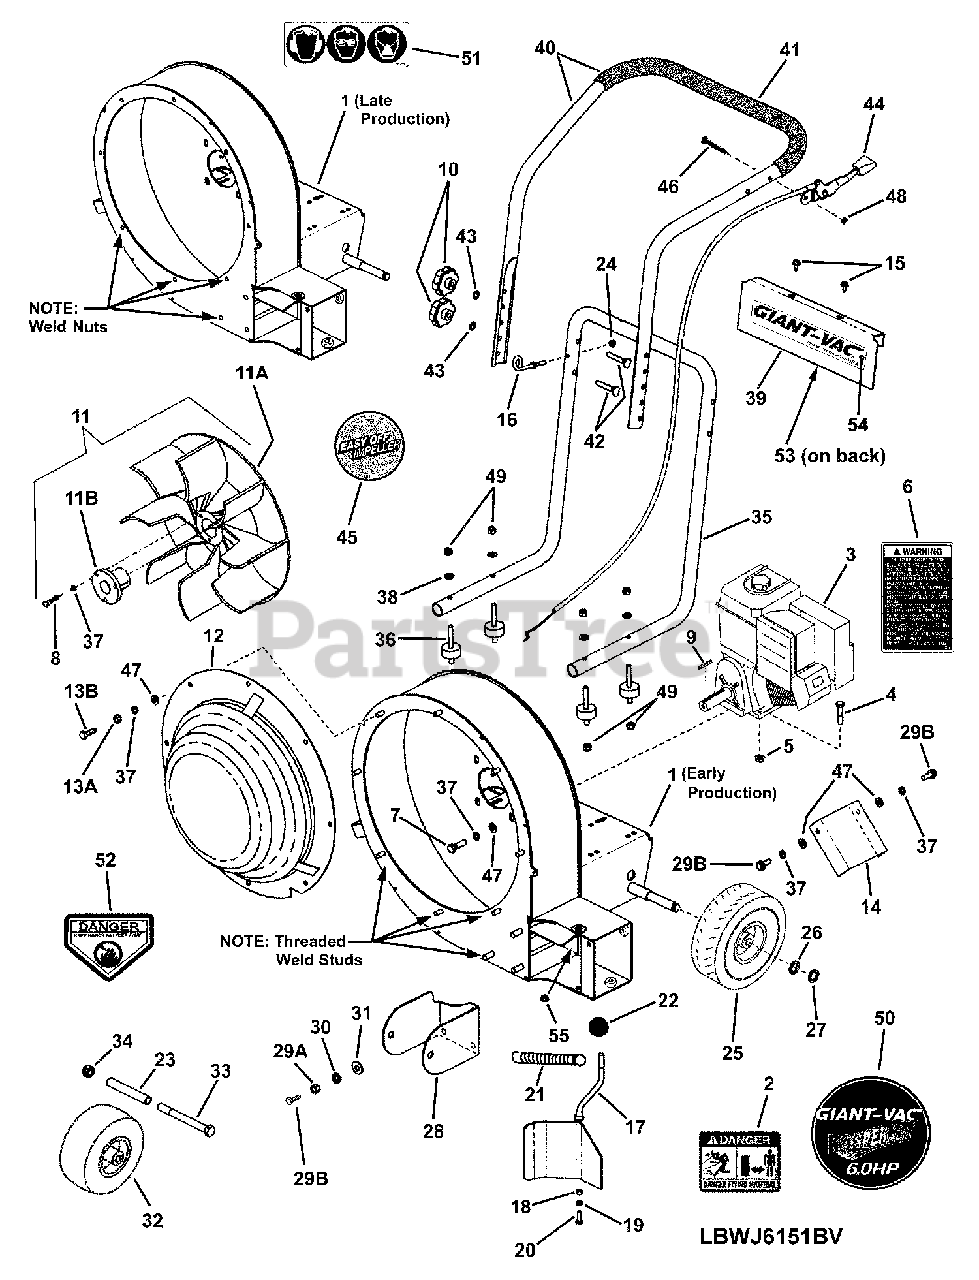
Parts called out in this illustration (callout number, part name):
1	WELDMENT, Housing- Extreme Blower
2	DECAL, Thrown Objects, Large
4	SCREW, 5/16-18 x 1-1/2 Hex Head Cap, GR 5
5	NUT, 5/16-18 Hex Flange Lock, GR 5
6	DECAL, Warning- Leaf Blower
7	SCREW, 5/16-24 x 1-3/4" Hex Head Cap, GR 5
8	SCREW, 5/16-18 x 1-1/4", Hex Head Cap, GR 5
9	KEY, 1/4" Square x 2"
10	KNOB, Fluted- Folding Handles
11	ASSEMBLY, 15" 8 Blade Impeller
11A	IMPELLER, Cast, 15" O.D. (9 curved alum. blades)
11B	HUB, Taper Loc, Type 1 (1.938 OAL)
12	WELDMENT, Intake Baffle- 60BWJ
13A	NUT, 5/16-18 Hex, GR 5 or B
13B	SCREW, 5/16-18 x 3/4" Hex Head Cap, GR 5
14	DEFLECTOR, Side Air
15	SCREW, 5/16-18 x 5/8" Hex Washer Self-Tap
16	GUIDE, Rope (1/4-20 thread)
17	** WELDMENT, Door Front/Side Discharge
18	BUSHING, Steel .250 ID x .375 OD x .25 Long
19	WASHER, 1/4" Split Lock
20	SCREW, 1/4-20 x 3/4" Hex Head Cap, GR 5
21	SPRING, Extension- Side Air Discharge Door
22	KNOB, Ball Hand Lever- 3/8-16 Metal Insert
23	TUBE, Front Wheel- Extreme
24	NUT, 1/4-20 Hex Center Lock, GR 5 or B
25	ASSY., Wheel & Tire 4.10/3.50-4 Kenda
26	WASHER, .64 x .99 x .05 Flat
27	RING, External Retaining (TRU1500-62)
28	BRACKET, Front Wheel Mounting
29A	NUT, 3/8-16 Hex, GR 5 or B
29B	SCREW, 3/8-16 x 1" Hex Head Cap, GR 5
30	WASHER, 3/8" Split Lock
31	WASHER, 3/8" Flat
32	ASSEMBLY, Tire & Wheel 9 x 350-4 "Flatfree"
33	BOLT, 1/2-13 x 5" Hex Head Cap
34	NUT, 1/2-13 Hex Center Lock, GR 5
35	HANDLE, Lower Folding- Wide- Blower
36	MOUNT, Vibration (5/16-18 thread- both ends)
37	WASHER, 5/16" Split Lock
38	WASHER, 5/16" Curved
39	DASH PANEL, Blower- Wide
40	ASSY, Upper Handle & Grip- Wide (p/n 7033696 + grip)
41	GRIP, 1.0 x 21-1/2" Foam
42	BOLT, Curved Head Square Neck 5/16-18 x 2" GR 2
43	WASHER, 5/16" Internal Tooth Lock
44	THROTTLE CONTROL, 35/1.62, Briggs
45	DECAL, Easy Off Impeller
46	SCREW, 1/4-20 x 2" Hex Head Cap, GR 5
47	WASHER, .34 x .69 x .08 Flat
48	NUT,1/4-20 Hex Nyloc
49	NUT, 5/16-18 Hex Nyloc
50	DECAL, 6 HP Whisper Jet
51	DECAL, Personal Protection
52	DECAL, Danger, Cut Finger
53	DECAL, GIANT-VAC (Small)
54	DECAL, GIANT VAC
55	BUSHING, Flanged .375 x .500 x .25 (.625 x .063 Flange)
